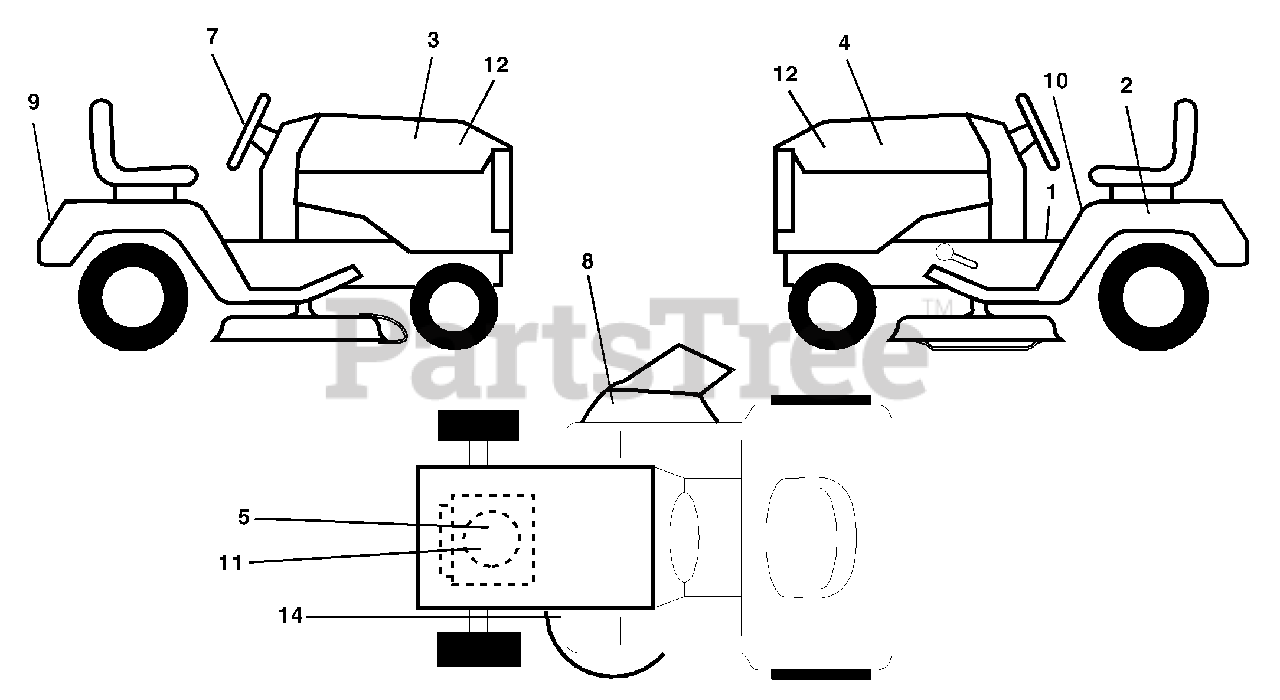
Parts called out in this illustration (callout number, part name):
1	Decal Oper. Step Thru E/F
2	Decal Battery
3	Decal Hood RH
4	Decal Hood LH
5	Decal HP Engine
7	Decal Wheel Steering
8	Decal Warning
9	Decal Fender Husq
10	Decal Fender Danger E/F
11	Decal Engine Logo
12	Decal Hood Sides Logo
14	Decal V-Belt Schematic
